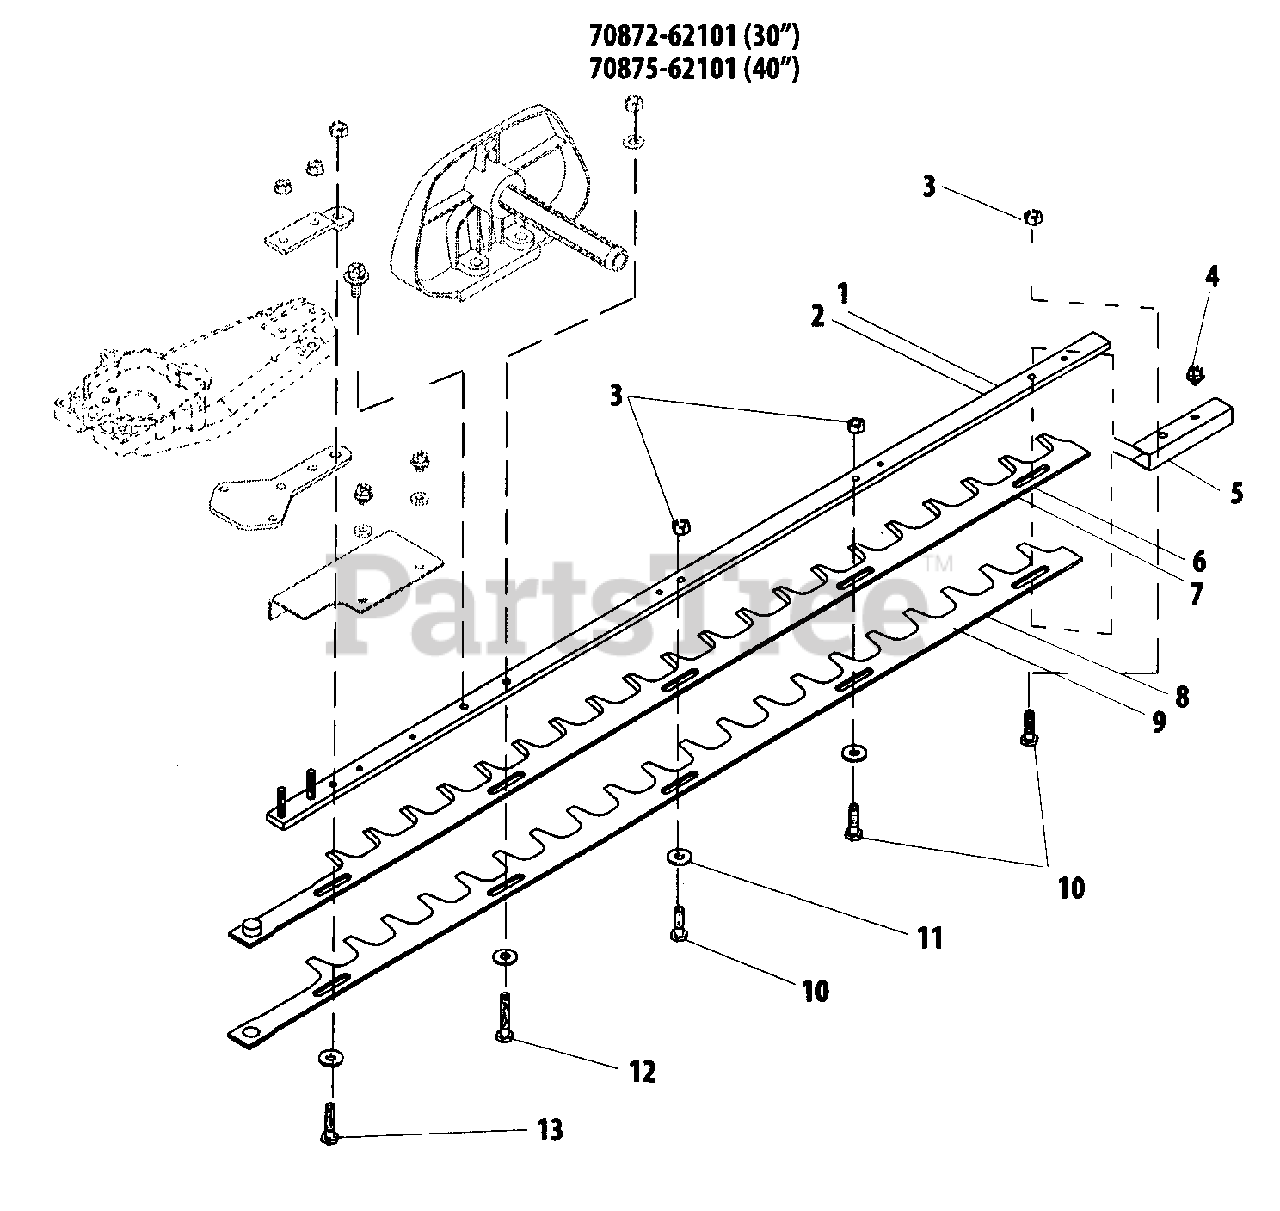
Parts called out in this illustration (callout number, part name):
1	GUIDE BAR - 30"
2	GUIDE BAR - 40"
3	NUT M6
4	BOLT M5×8
5	PLATE, GUIDE
6	BLADE, TRIMMER - 30" -- UPPER
7	BLADE, TRIMMER - 40" -- UPPER
8	BLADE, TRIMMER - 30" -- LOWER
9	BLADE, TRIMMER - 40" -- LOWER
10	BOLT M6×20
11	WASHER M6
12	BOLT M6×32
13	BOLT
70872-62101	TRIMMER BLADE KIT - 30"
70875-62101	TRIMMER BLADE KIT - 40"
